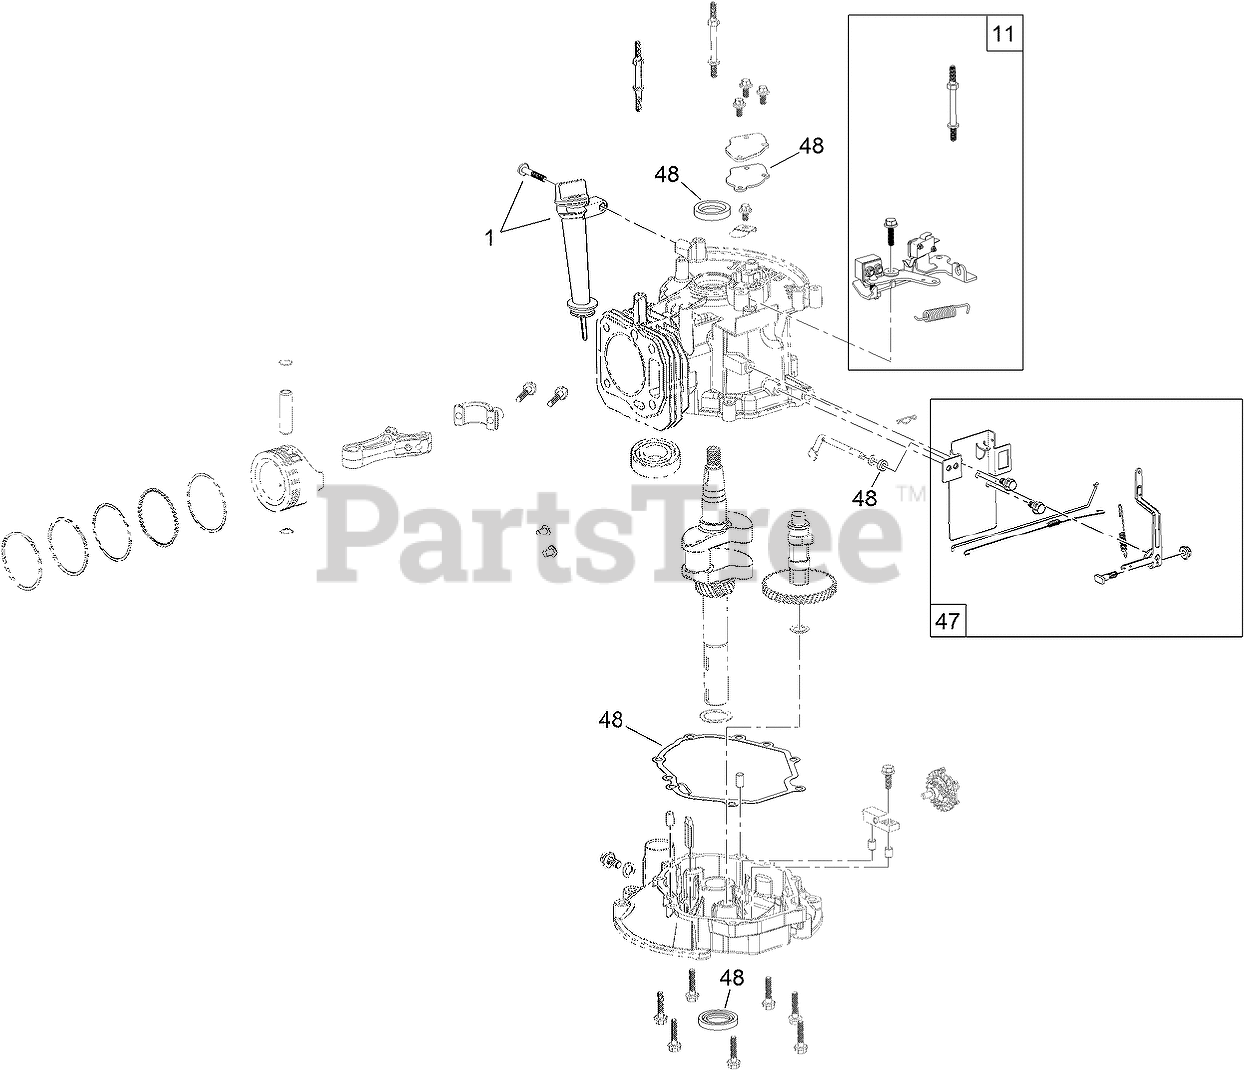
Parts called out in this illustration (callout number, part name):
1	DIPSTICK AND FILL TUBE KIT
11	BRAKE KIT
47	GOVERNOR ARM KIT
48	SEAL AND GASKET KIT
